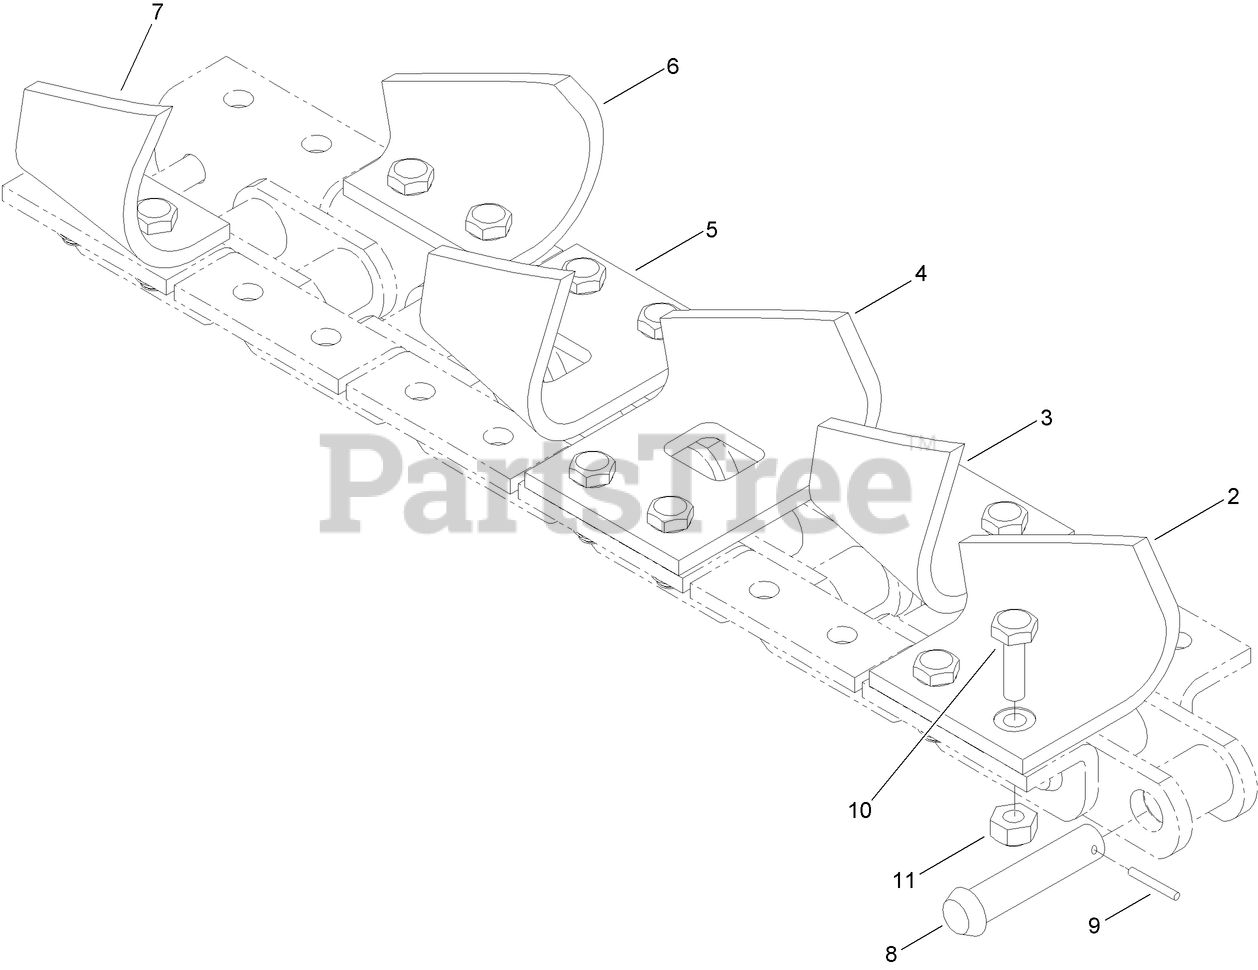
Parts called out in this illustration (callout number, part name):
2	TOOTH-CUP (1"-8" L)
3	TOOTH-CUP (1"-8" R)
4	TOOTH-CUP (3" L)
5	TOOTH-CUP (3" R)
6	TOOTH-CUP (6" L)
7	TOOTH-CUP (6" R)
8	PIN-MASTER
9	PIN-KEEPER, MASTER
11	NUT-LOCK
